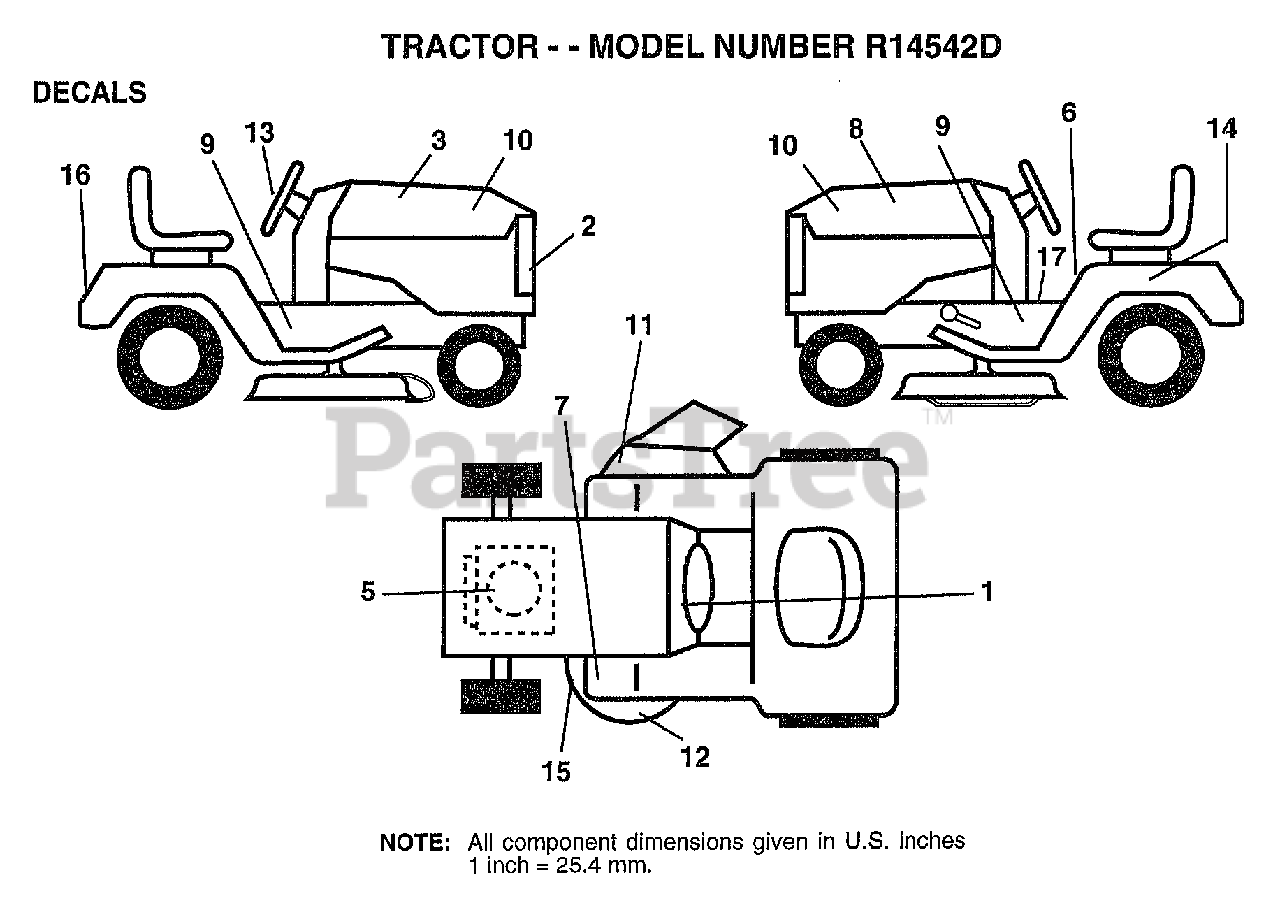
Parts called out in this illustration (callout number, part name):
1	DECAL.INSTR.FRENC
2	GRILL DECAL
3	DECAL.HD.RH.RALLY
5	DECAL, ENGINE
6	DECAL.CAUT.ENG/FR
7	DECAL T
8	DECAL.HD.LH.RALLY
9	CHASSIS DECAL
10	DECAL.INS.HD.RALL
11	"DECAL, WARNING"
13	"DECAL,STR WHL"
14	DECAL.BATRY.3-3908
15	"DECAL-SCHEM,BELT"
16	FENDER DECAL
17	DECAL BRAK PARK
